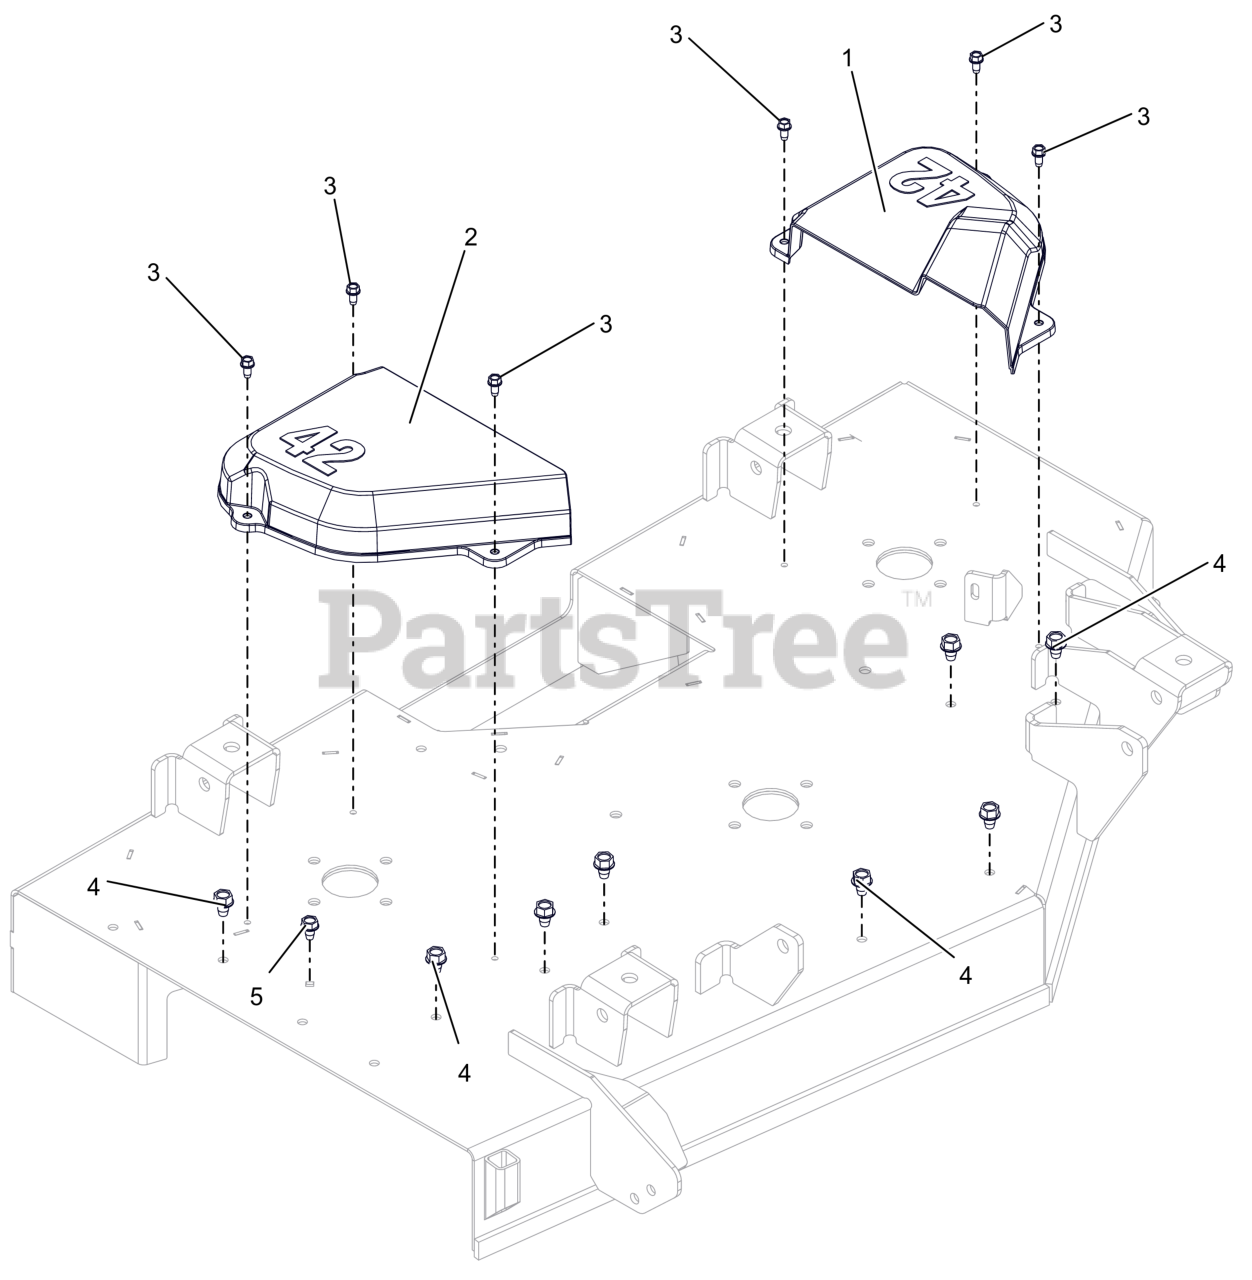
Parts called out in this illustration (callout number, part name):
1	COVER, BELT 42" LH
2	COVER, BELT 42" RH
3	SCR-TAP .25-20X.50 HWH ZCC
4	SCR,TAP .375-16X.50 HWH TR ZCC
5	SCR,TAP .312-18X.50 HWH TR ZCC
